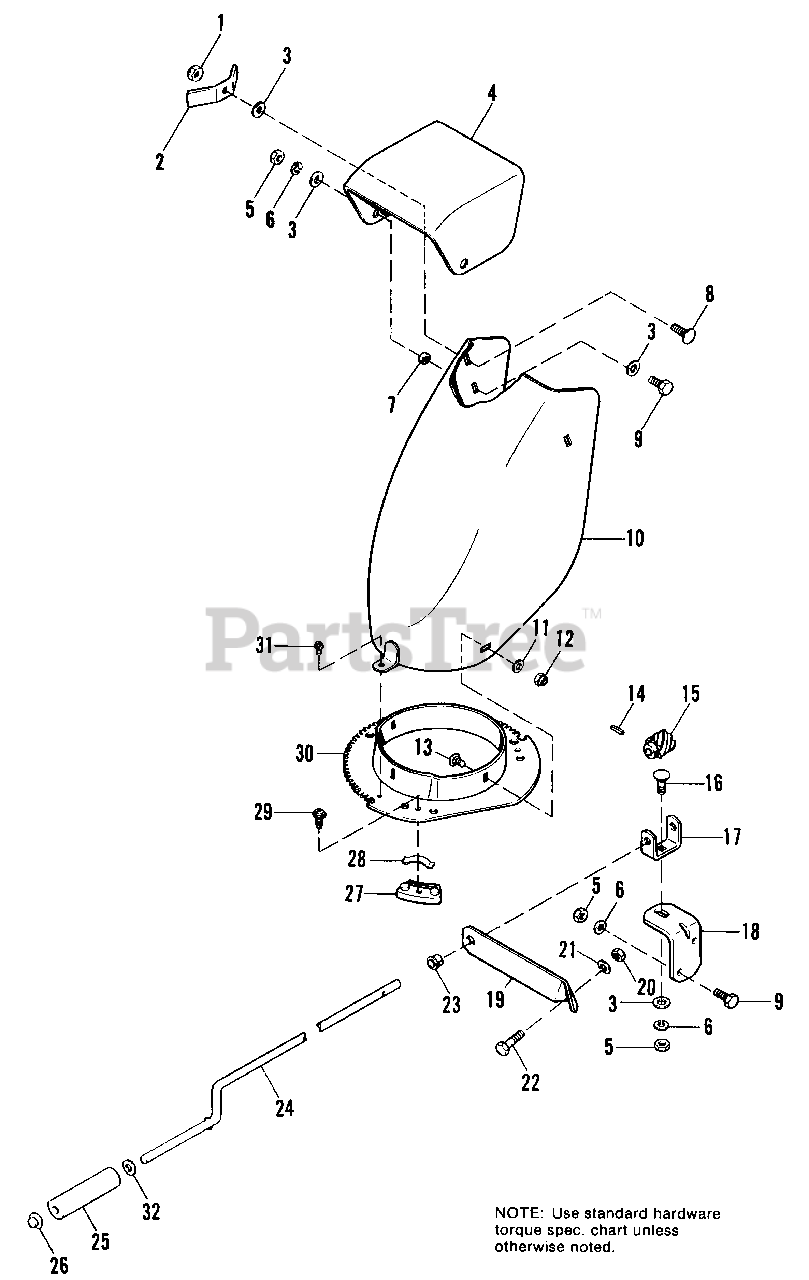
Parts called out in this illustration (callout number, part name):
1	LOCKNUT, Hex, 5/16-18
2	NUT, Wing, 5/16-18
3	WASHER, Plain, 5/16
4	DEFLECTOR, Chute
5	NUT, Hex, Full, 5/16-18
6	LOCKWASHER, 5/16
8	BOLT, Carriage, 5/16-18 x 1
9	CAPSCREW, Hex, 5/16-18 x 3/4
10	CHUTE ASSY.
11	WASHER, Plain, 1/4
12	LOCKNUT, Nylon. 1/4-20
13	BOLT, Carriage, 1/4-20 x 5/8
14	PIN, Spring, 1/8 x 3/4
16	BOLT, Carriage, 5/16-18 x 3/4
17	BRACKET, Worm
18	BRACKET, Worm Support
19	BRACKET, Chute Control
20	NUT, Hex, Full, 1/4-20
21	LOCKWASHER, 1/4
22	CAPSCREW, Hex, 1/4-20 x 1-1/2
23	BUSHING, Plastic
24	ROD, Chute Control
25	HANDLE, Plastic
26	PALNUT
27	HOLD DOWN, Chute
29	SCREW, Plastic, #10
30	GEAR, Chute
31	SCREW, Hex, Taptite, 1/4-20 x 3/8
32	WASHER, Plain, 3/8
